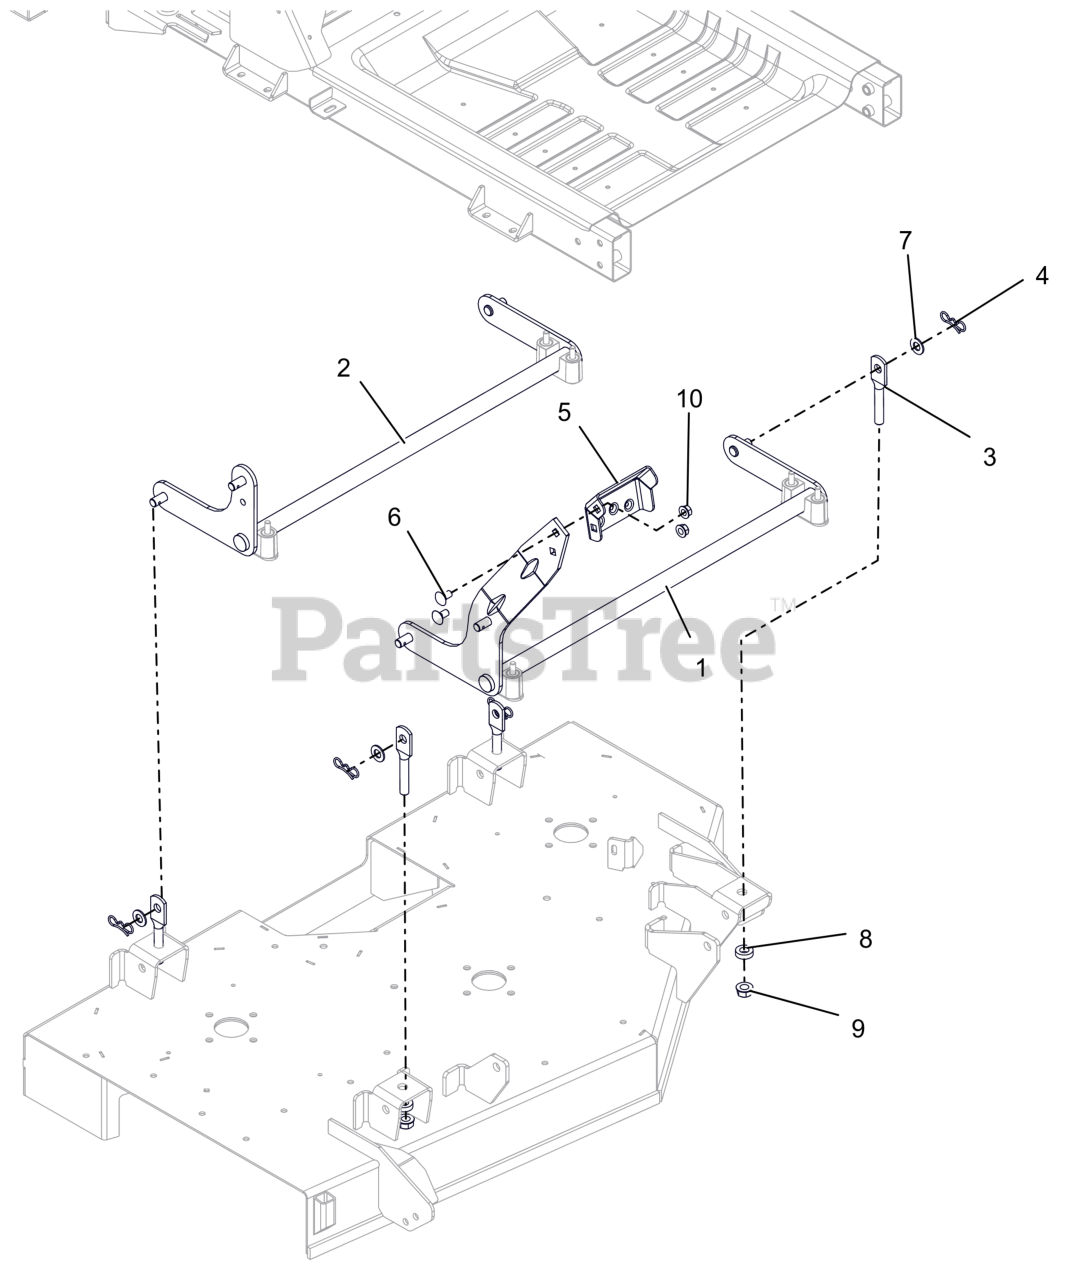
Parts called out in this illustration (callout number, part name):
1	WLDMT, FRONT DECK LIFT PIVOT
2	WLDMT, REAR DECK PIVOT
3	LINK, DECK (HOLE-SHORT)
4	PIN, BOWTIE .091X1.875 ZCC
5	PEDAL, DECK LIFT (BOLT ON)
6	BLT,RHSN .38-16X.75 G5 BFP
7	WSHR-FL-NYL .518X1.000X.080
8	WSHR, RUBBER
9	NUT-LK-CTR-FLG .500-13 GG ZCC
10	NUT-LK-CTR-FLG .375-16 GF ZCC
